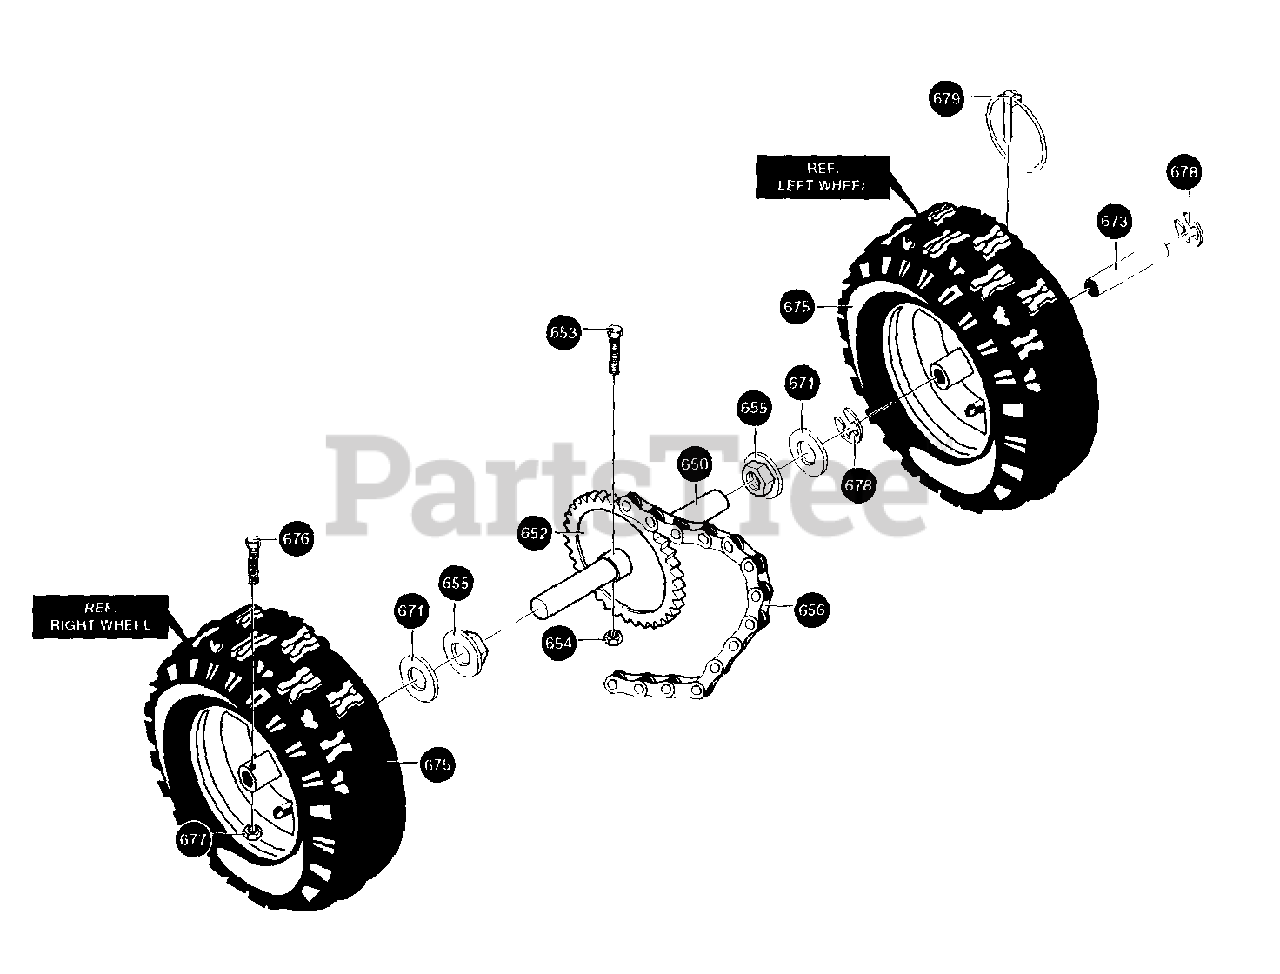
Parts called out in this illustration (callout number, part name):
650	SHAFT, AXLE
652	SPROCKET, HUB
653	SCREW, 1/4-20 X 2.25
654	NUT, 1/4-20 RGHXCTRLK
655	BEARING, FLANGED
656	CHAIN, ROLLER
671	FLATWASHER .765 X 1.12 X .06
673	BUSHING, WHEEL
675	TIRE & RIM
676	SCREW, 1/4-20 X 1.75
677	NUT, 1/4-20 RGHXCTRLK
678	RING, RETAINING
679	PIN KLIK .25 X 1.38 DIA
